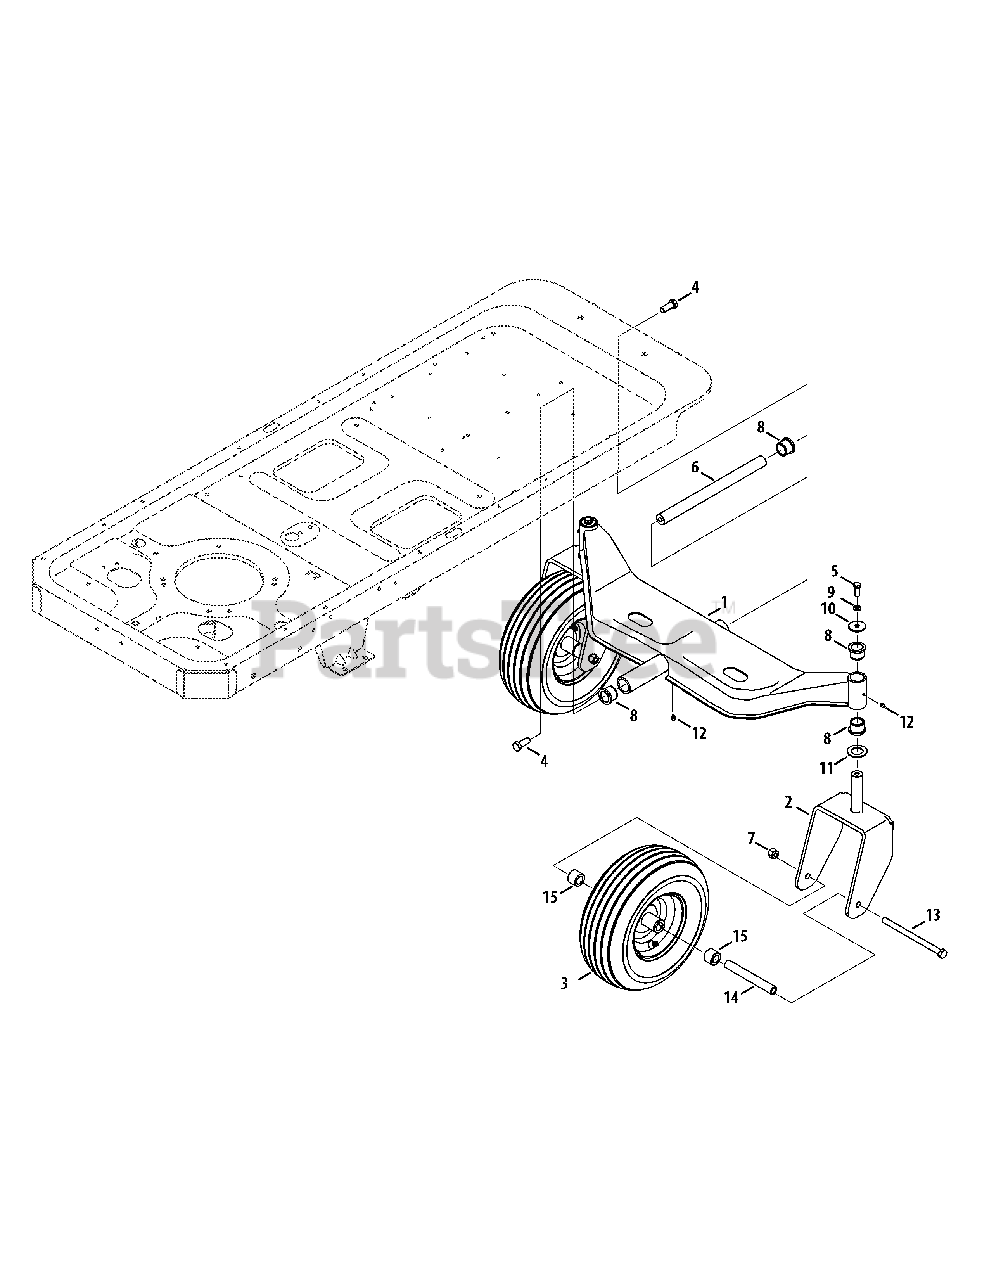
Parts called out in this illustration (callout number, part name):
1	Front Pivot Axle
2	Castor Wheel Bracket
3	Wheel Assembly, 11 x 4 x 5
4	Hex Lock Screw, 1/2-13 x 1.25
5	Hex Cap Screw, 3/8-16 x 1.0
6	Axle Shaft
7	Hex Lock Nut, 1/2-13
8	Flange Bearing, 1.0 x 1.246
9	Lock Washer, 3/8
10	Flat Washer, .39 x 1.5 x .134
11	Flat Washer, 1.0 x 1.75 x .107
12	Lube Fitting, 3/16
13	Bolt, 1/2-20 x 7.25
14	Spacer, 51 x .75 x 5.825
15	Hub, .76 x 1.23 x .92
